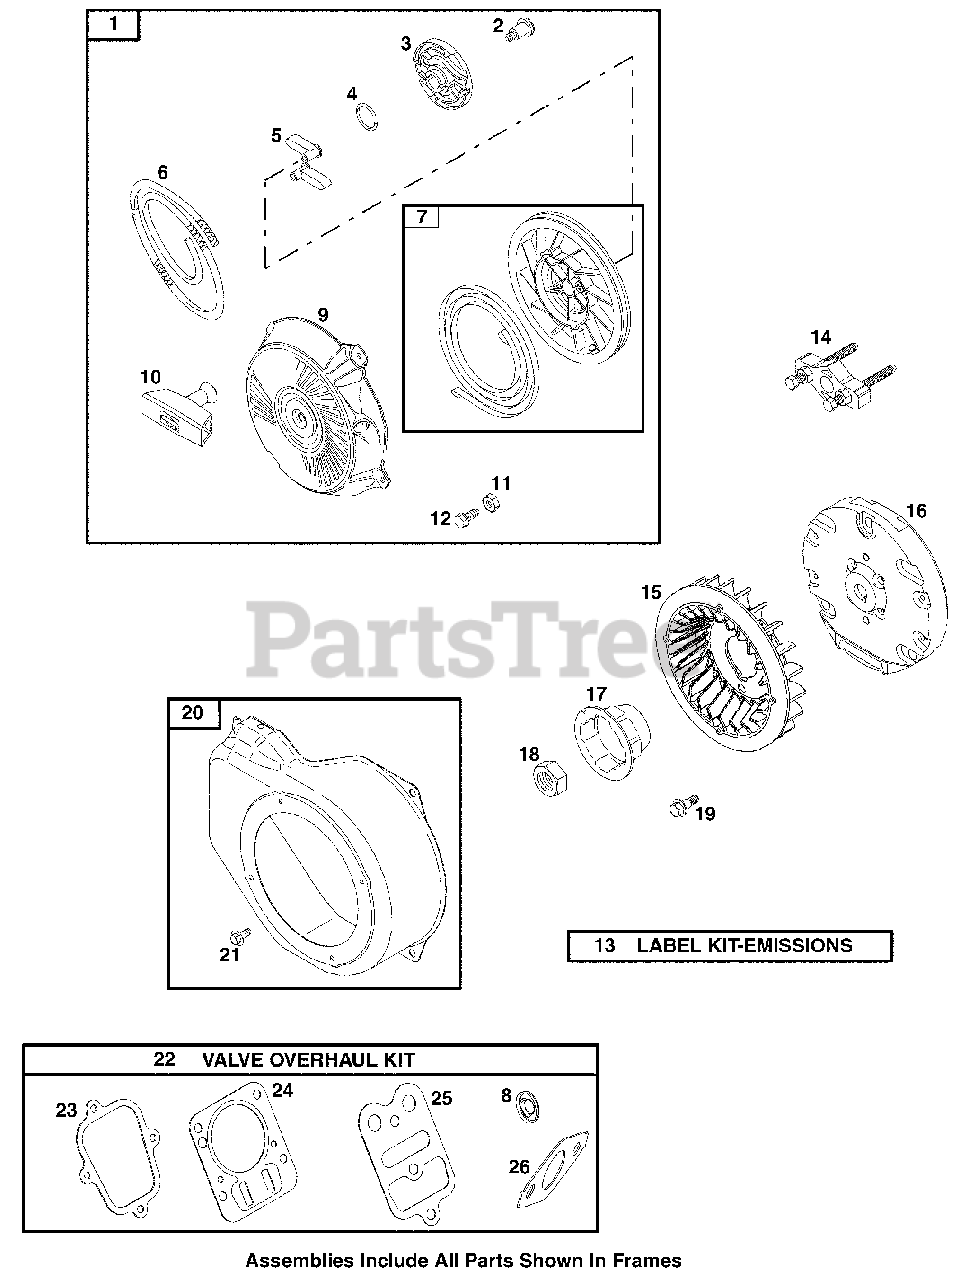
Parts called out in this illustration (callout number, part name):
1	Starter-Rewind
2	Screw
3	Plate-Pawl Friction
4	Spring-Friction
5	Pawl-Ratchet
6	Rope-Starter
7	Pulley/Spring Assembly
8	Seal-Valve
9	Rewind Starter Housing
10	Starter Rope Grip
11	Nut
12	Screw
13	Emissions Label
14	Flywheel Puller
15	Fan-Flywheel
17	Cup-Flywheel
18	Nut
19	Screw
20	Housing-Blower
21	Screw
22	Kit-Valve Overhaul
23	Gasket-Rocker Cover
24	Cylinder Head Gasket
25	Cylinder Head Plate Gasket
26	Gasket-Intake
